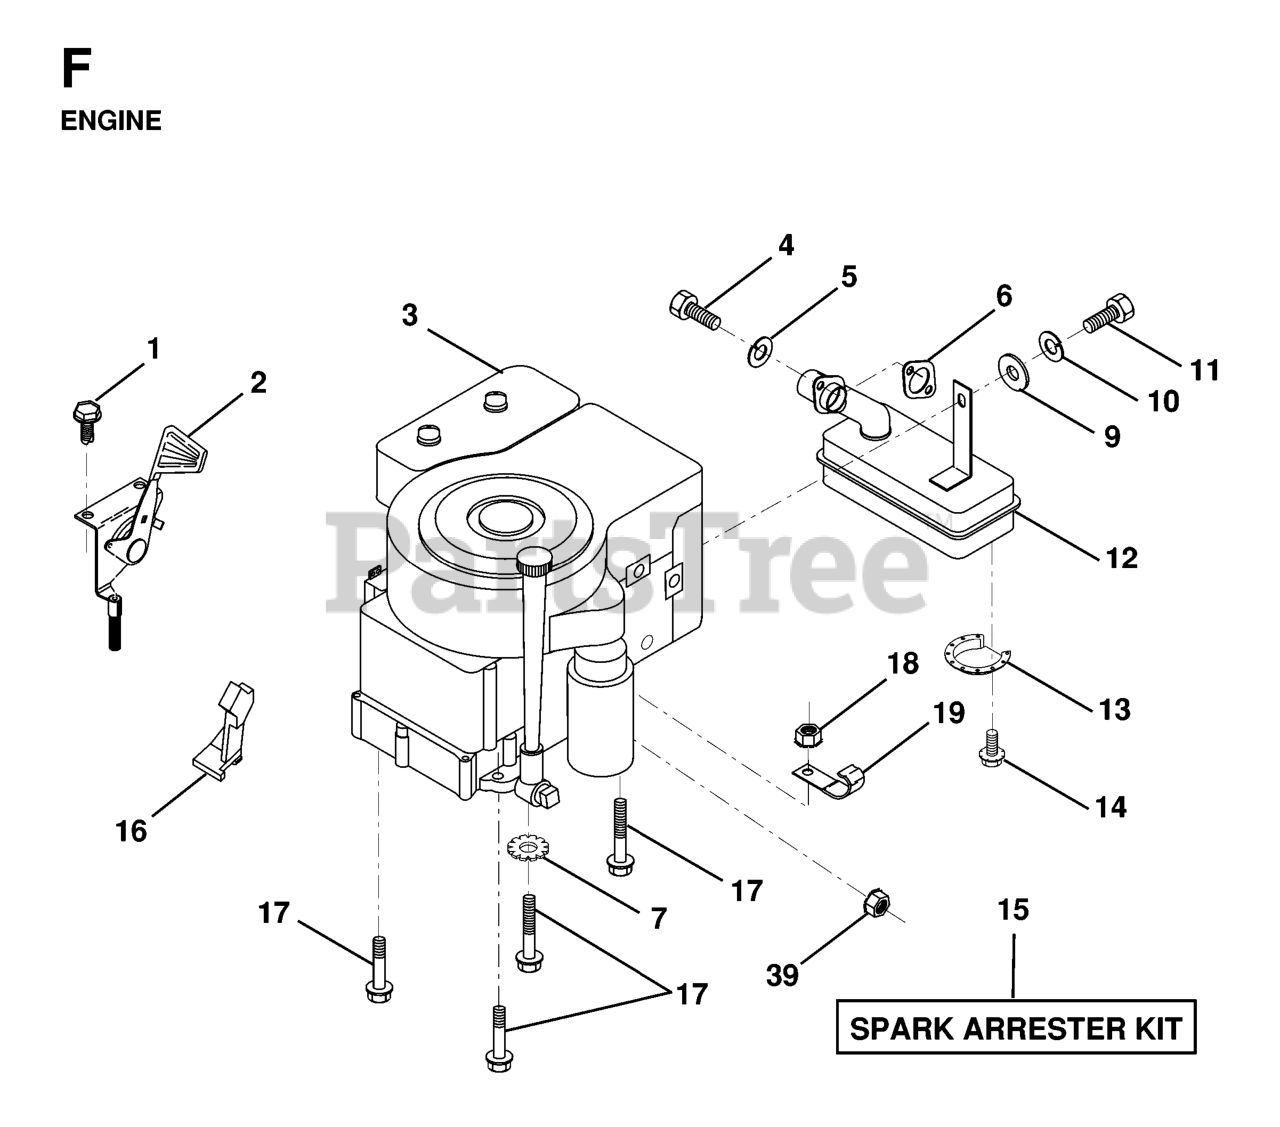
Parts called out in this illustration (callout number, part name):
2	CONTROL.TH/CH.RH.BLK.FLG.EEC
4	SCREW
5	WASHER.LOCK.HVY.HLCL.SPR.5/16
6	GASKET.ENG.1.313 ID.TIN PLATED
7	LOCKWASHER
9	WASHER
10	LOCKWASHER
12	MUFFLER.SINGLE.B&S.12HP
13	DEFL MUFFLER LTV
14	SCREW
15	KIT.SPARK ARRESTOR 794945 B&S
16	STOP THROTTLE
17	SCREW LT
19	CLIP T
39	NUT FLANGE 1/4-20 STARTER NUT
